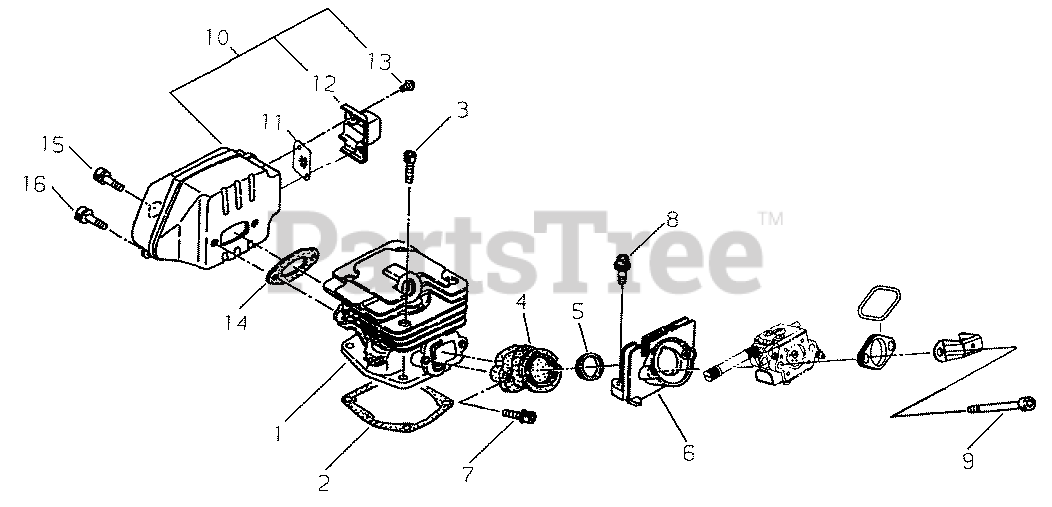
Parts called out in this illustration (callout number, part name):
2	GASKET, CYLINDER
4	BOOT
5	SLEEVE
6	BRACKET
7	SCREW - 4X12
8	SCREW - 4X14
9	SCREW - 5X50
10	MUFFLER SUB ASSY
11	SCREEN, SPARK ARRESTOR
12	GUIDE, EXHAUST
13	SCREW - 4X6
14	GASKET, EXHAUST
15	SCREW - 5X16
16	SCREW - 5X16
